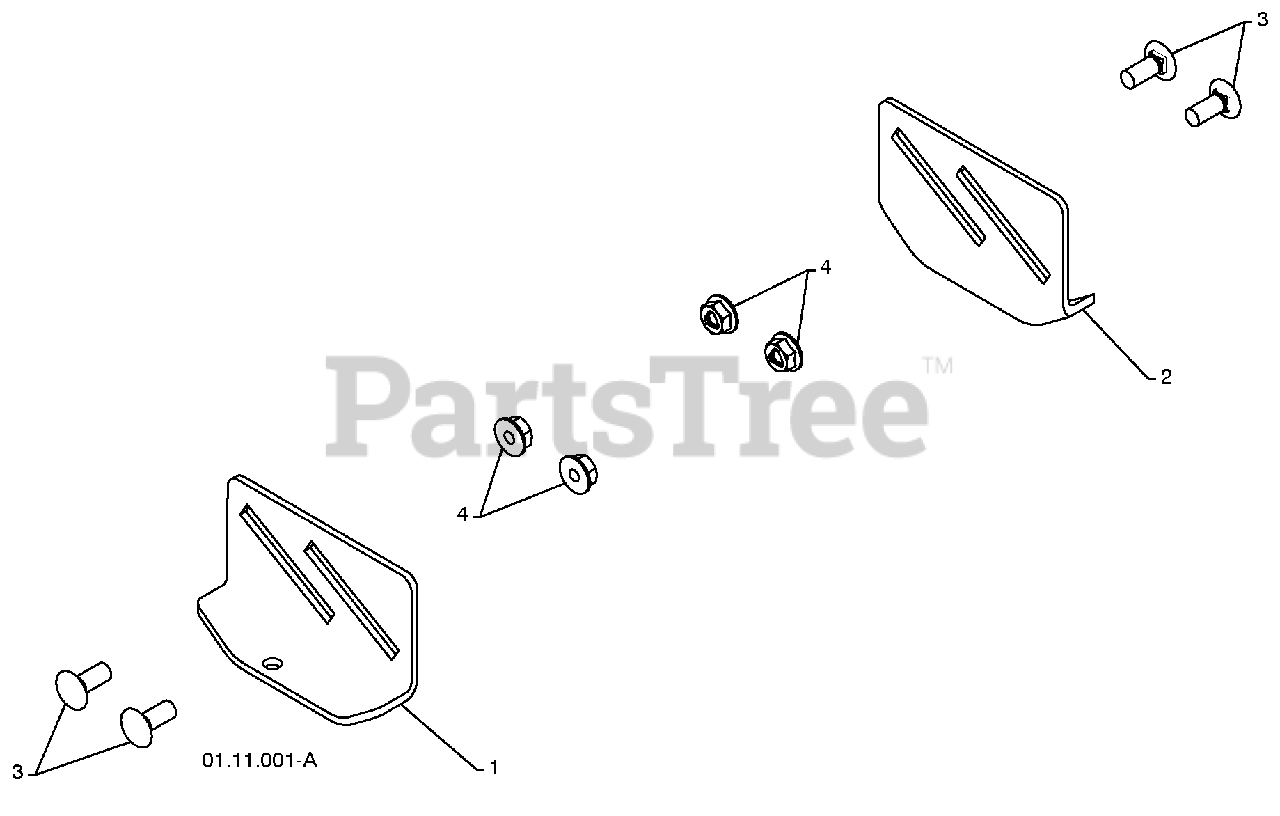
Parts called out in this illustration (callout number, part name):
1	SKID PLATE LH
2	SKID PLATE RH
3	CARRIAGE BOLT 5/16-18 X .75
4	NUT 5/16-18
